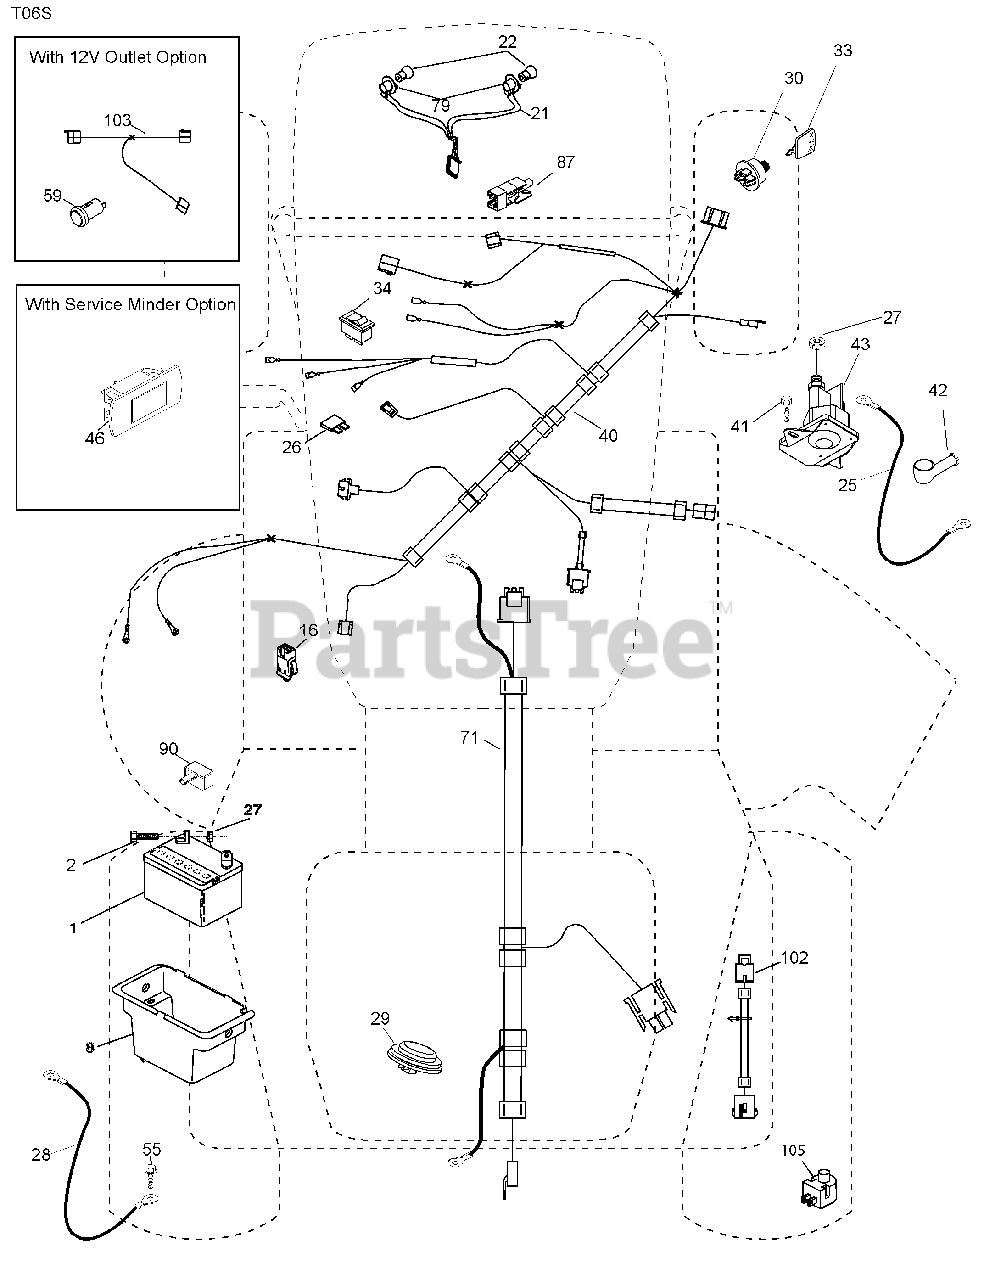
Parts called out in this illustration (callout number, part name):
1	Battery
2	Bolt Hex Head 1/4-20 x 3/4
8	Box Battery
16	Switch Interlock Push-In
21	Harness Socket Light w/4152J
22	Bulb Light
25	Cable Starter
27	Nut Keps Hex 1/4-20 unc
28	Cable, Ground
29	Switch, Seat
30	Switch, Ign
34	Switch Light/Reset
40	Harness Ign.
41	Screw Thd Cut 1/4-20 x 1/2
42	Cover, Terminal
43	Solenoid
46	Gauge Servicereminder Hrmtr
55	Screw Thdrol 5/16-18 x 3/4 TYTT
71	Harness Ign. Dash
79	Socket Asm. Bulb
87	Switch Interlock Clutch
90	Cover Terminal
102	Harness Pigtail
